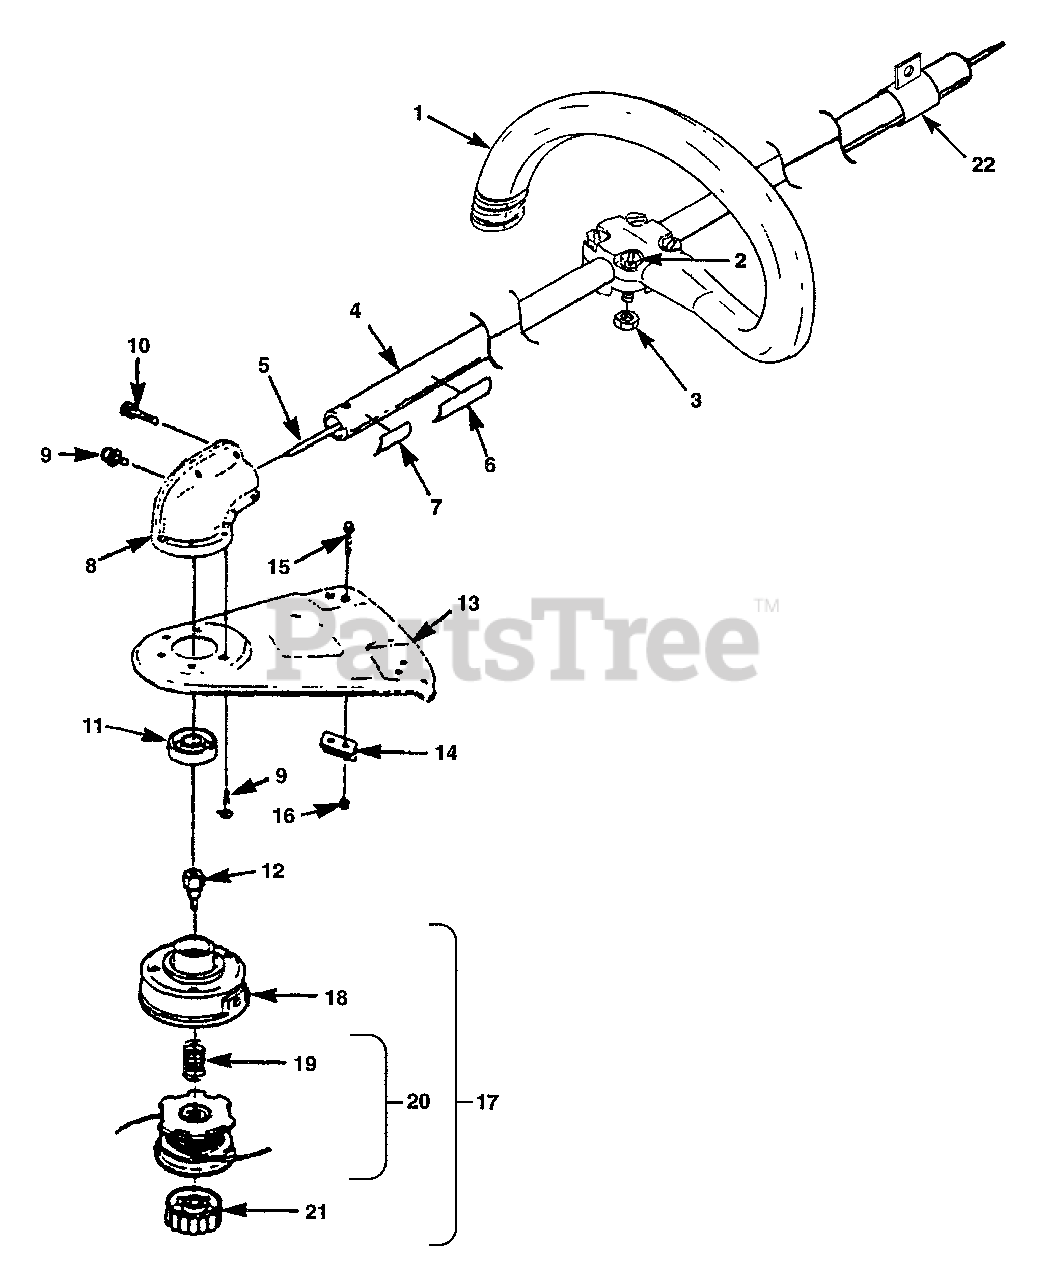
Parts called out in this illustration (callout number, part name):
1	FRONT HANDLE ("G")
2	SCREW-Hex Hd. (10-24 X 1")
3	NUT-Hex (10-24)
4	HOUSING-Drive Shaft
5	SHAFT-Flexible
6	DECAL-Starting Inst.
7	DECAL-Warning
8	GEAR HEAD
9	SCREW-Taptite (10-24 X 1/2")
10	SCREW-Hex Hd. (10-24 X 5/8")
11	WASHER-Flanged
12	ADAPTOR-Shaft
13	GRASS DEFLECTOR KIT
14	BLADE-Cut-Off
15	SCREW-Machine Hex Hd. (10-24 X 3/8")
16	NUT-Hex (10-24)
17	STRINGHEAD COMPLETE (080" Line)
18	HOUSING & EYELET (Dual Line)
19	SPRING-Compression
20	SPOOL & STRING (.080" Line)
21	RETAINER-Spool (R.H. Thread, Black)
